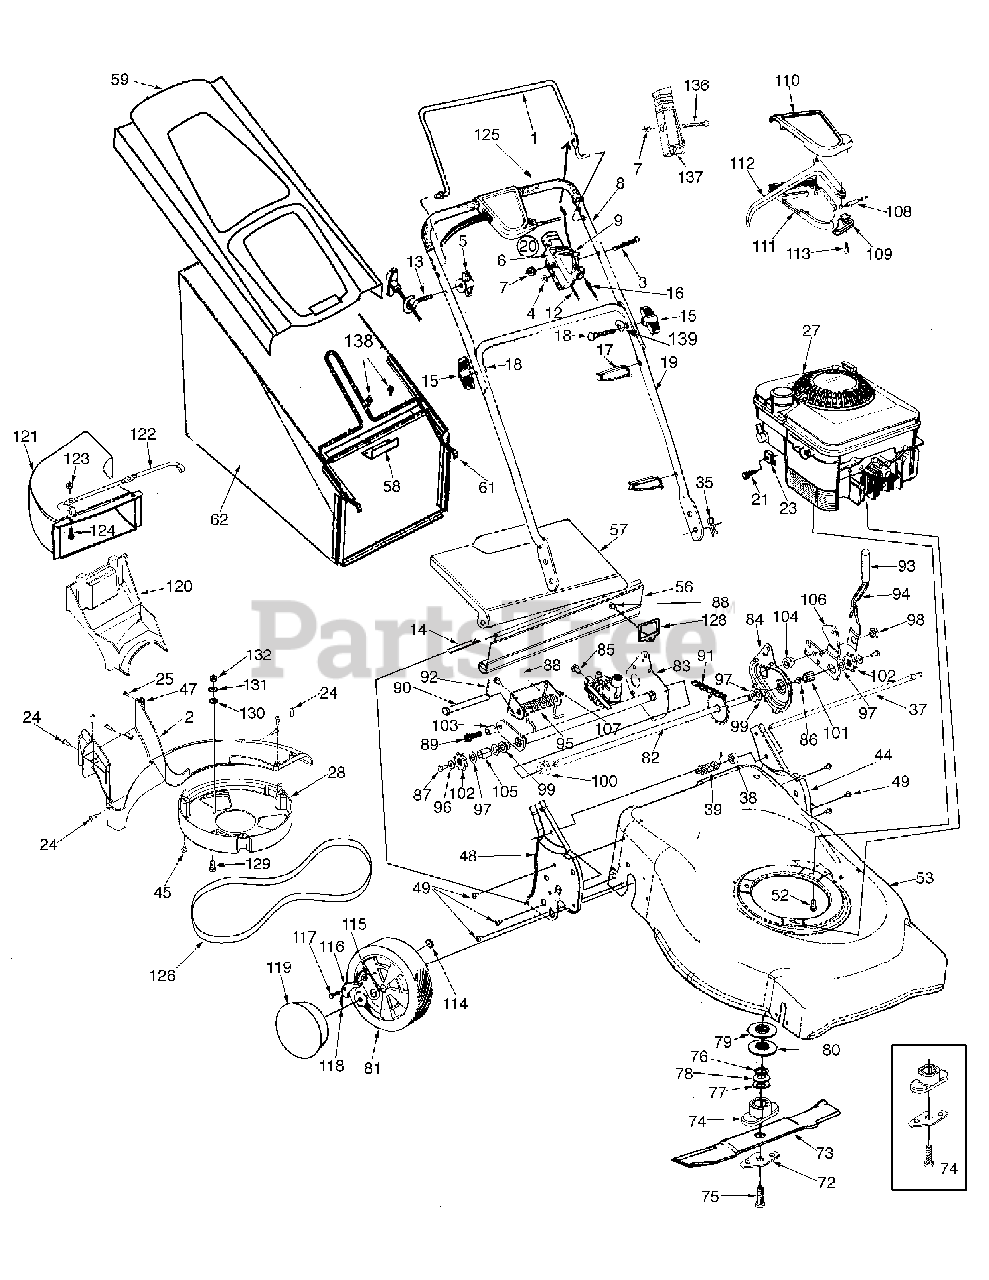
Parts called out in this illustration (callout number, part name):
2	Baffle
3	Oval C-Sunk Mach-Screw
4	Spring Washer .66"ID
5	Handle Knob 1/4-20 Thd.
6	Throttle Body
7	Hex L-Nut 1/4-20
9	Throttle Lever
12	Throttle Control Wire - 47"
12	Throttle Control Wire - 55"
12	Throttle Control Wire - 60"
13	Rope Guide
14	Wire-47" Lg.
15	Hand Knob
16	Control Cable-45"
17	Cable Tie
18	Cr.Hd. Bolt 5 / 16-18 x 2" Lg.
20	Throttle Assy. (Incl. 3,4,6,7,9)
21	Hex Self-Tap Scr. #10-32 x.62"
21	Hex Sems Scr. #10-32 x.3"
22	Spark Plug Boot
23	Cable Clamp
24	Screw H.L. 12-24
25	Screw Mach. B Tapp.
28	Belt Cover
35	Int. Cotter Pin 5/15" Dia.
37	Pivot Rod
38	Spacer .385 I.D.
39	Torsion Spring L.H.
47	U-Nut
52	Hex L-Wash. Hd. Scr. 3/8-16 x 1 inch
62	Grass Bag - Black
72	Blade Bell Support
73	21" Mulching Blade w/Star
74	Blade Adapter
74	Blade Adapter Kit w/Star
75	Hex Bolt 3/8-24 x 2.5 Lg.
76	Spacer
77	Fl. Wash. .885 x 1.85 x .06
78	Spr. Wash. .890 x .7x .04
79	Pulley Half - Upper
80	Pulley Half - Lower
81	Wheel Assembly
82	Axle Assy: RR
86	Scr. TT 1/4-20
87	Hx Cap Screw 1/4-20
88	Screw 1/4-20 x.625
89	Scr 3/8 - 16 x 1.25
90	Pin - Clv. .500 Dia.x.4.62 Lg.
91	Chain:Endless 48:.500P x 22 Lg.
92	Pin-Cotter .125 O.D. x .75
93	Grip-Foam
94	Spring Lever
95	Torsion Spring
96	Bell Washer .265 x .75 x .062
97	Wash.Flat.508 I.D. x 1.0 O.D.
98	Nut - Shoulder .625 x .165 Lg.
99	Bearing-Flg Hex
100	Bearing-Flg. Hex
101	Bearing-Sleeve
102	Ratchet Wheel
103	Spacer - .385 x .625 x .700
104	Spacer-Shld. .385 I.D.x .715 Lg.
105	Spacer Slv. .520 I.D. x .950 Lg.
109	Mounting Cap
110	Control Cover - Upper
111	Control Cover - Lower
112	Lever
113	Screw #10-16 x.625
114	Weld Top L. 1/4-20
115	Pawl Plate
116	Pawl R.H.
117	Shldr. Scr. .340x.285
118	Spring, Ratchet
119	Hub Cap (Spoke Grey)
119	Hub Cap (Euro Grey)
120	Mulch Plug
121	Chute Deflector
122	Chute Mounting Rod
123	Hex-L-Nut 1/4-20 thd
124	Mach. Scr. 1/4-20
125	Foam Grip
126	Belt
130	Lockwasher 1/4" Reg.
131	Fl. Wash. .271 x .630 x .065
132	Nut 1/4-20
136	Scr. 1/4-20:1.31 Lg.
136	Scr. 1/4-20:1.75 Lg.
137	Housing (w/o Throttle)
138	Hex Washer Screw 1/4-20 x.625
139	Saddle Washer
